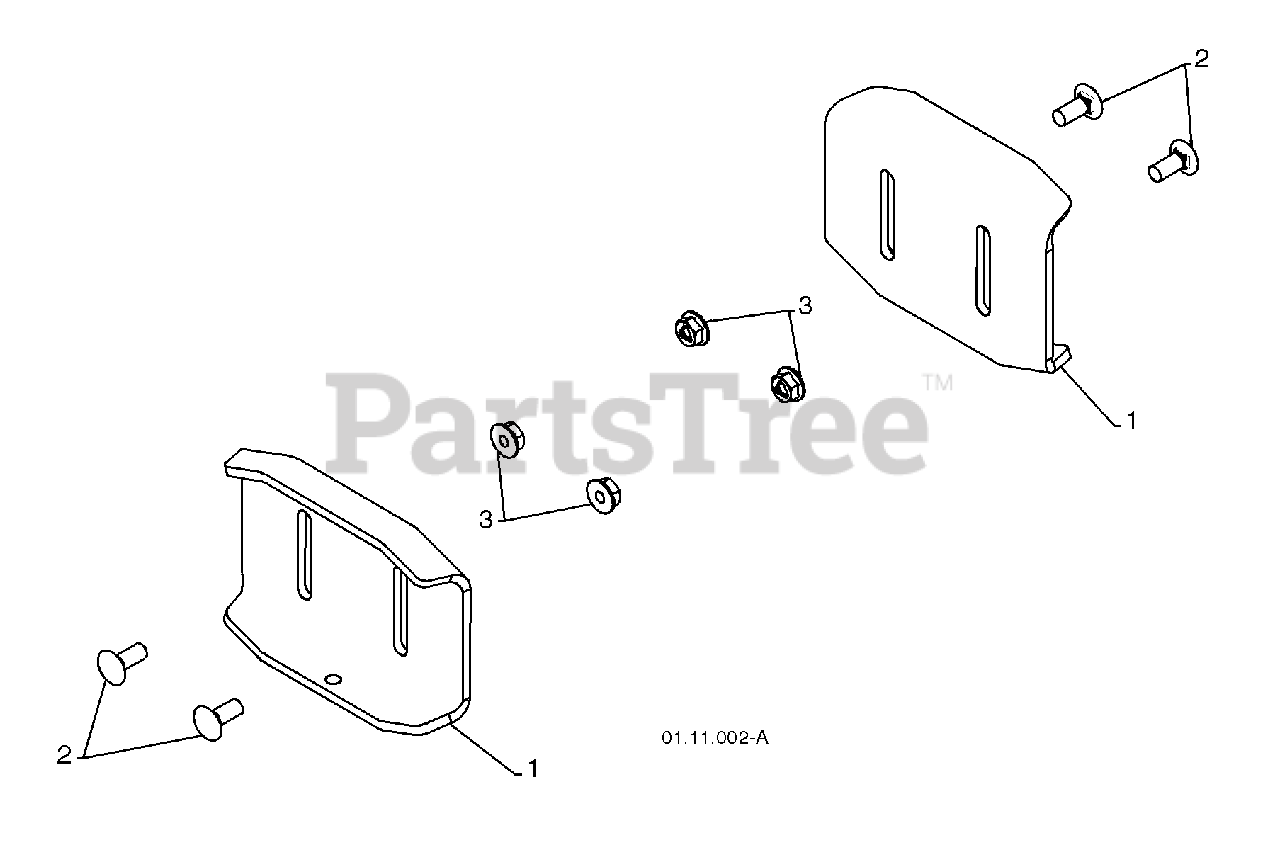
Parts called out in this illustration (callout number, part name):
1	SKID PLATE
2	CARRIAGE BOLT 5/16-18 X .750
3	NUT 5/16-18
